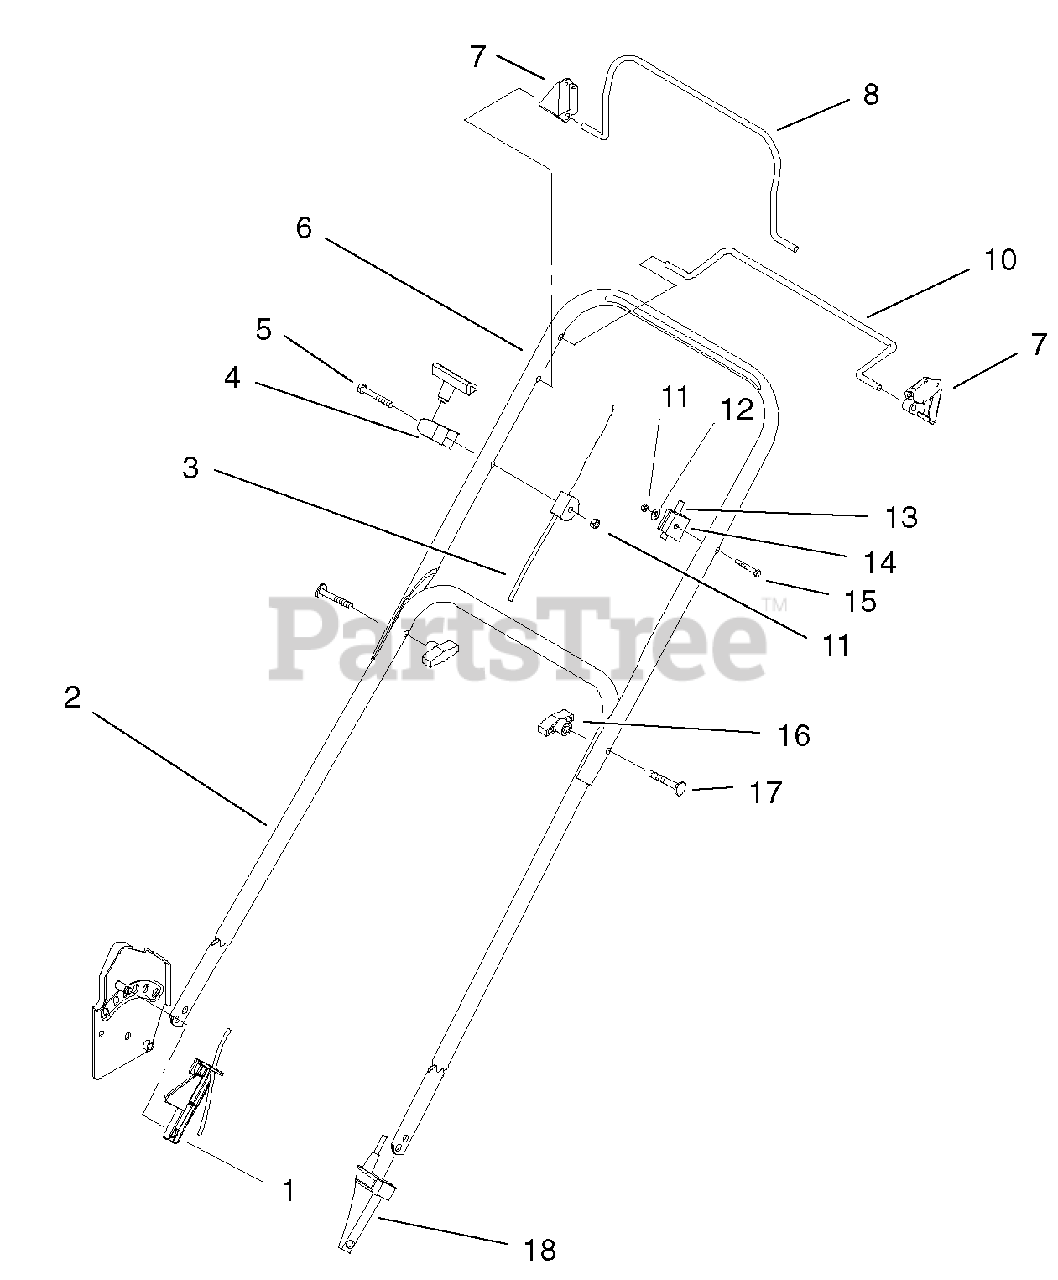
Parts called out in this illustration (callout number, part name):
1	Guard-Cable
2	Handle-Lower
3	Brake Cable ASM
4	Guide-Rope
5	Screw-HH
6	Handle-Upper,Es
7	Stop-Pivot
8	Bail-Brake
10	Bail-Control
11	Nut-Lock, NI
12	Washer-Flat
13	Cable-Ground Speed
14	Anchor-Upper, Cable
15	Screw-Handle
16	Knob-Handle
18	Anchor-Cable
